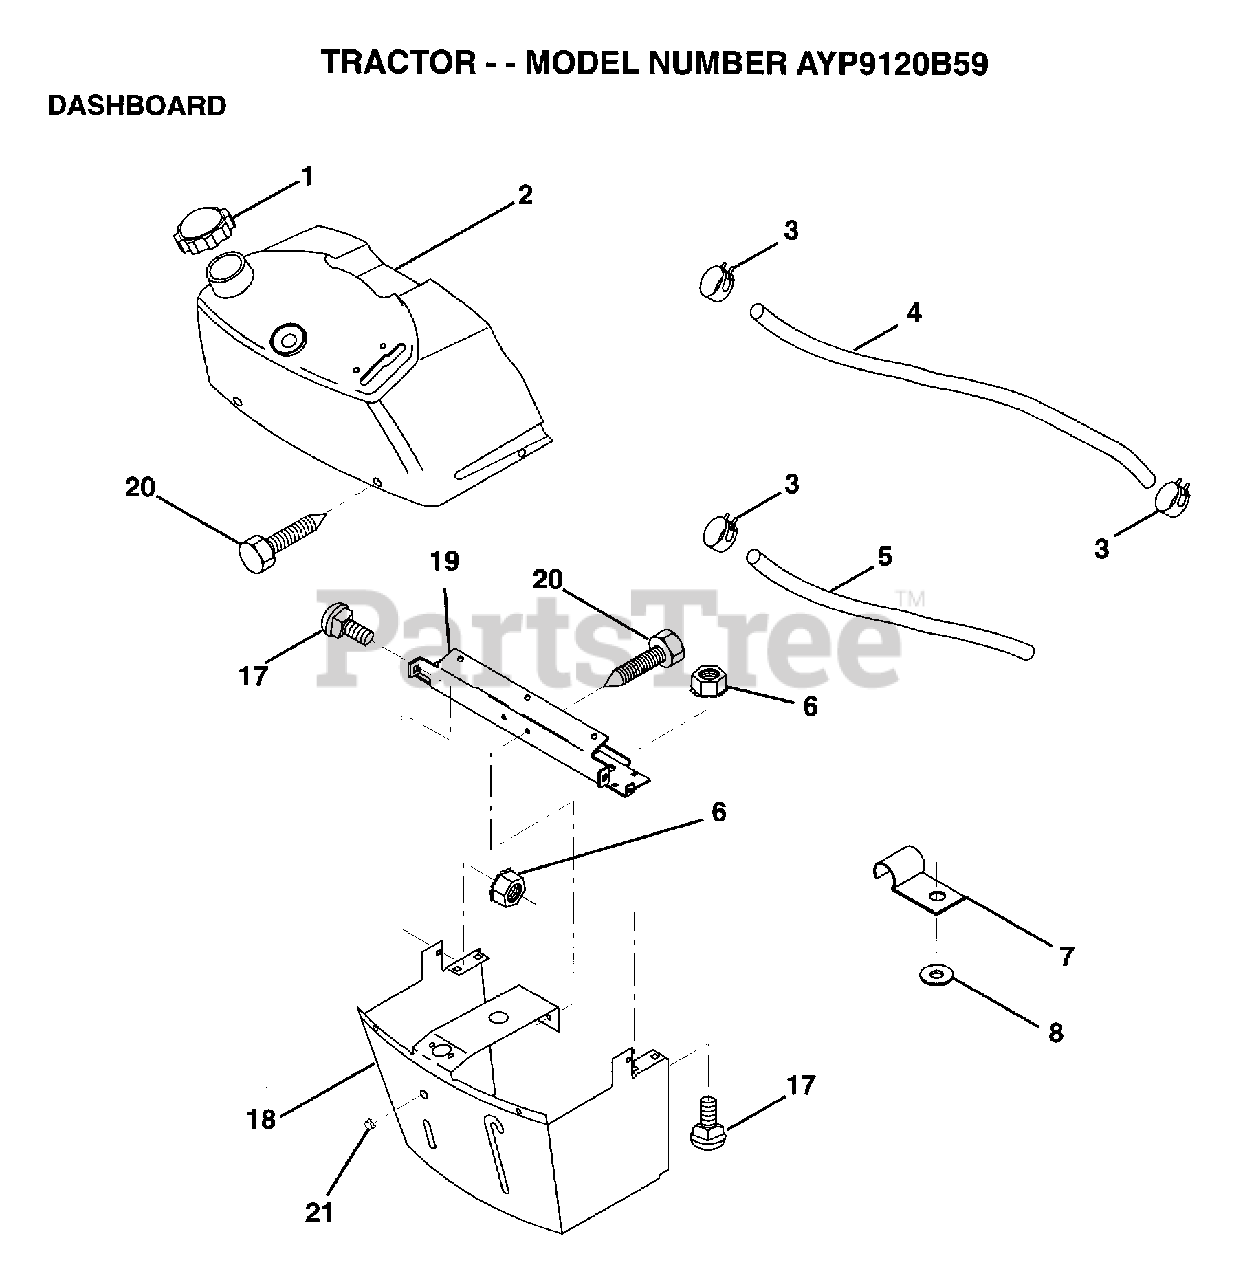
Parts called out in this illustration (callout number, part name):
1	CAP BLK FUEL LR
2	TANK.ASM.DASH.LR
3	HOSE CLAMP
5	FUEL LINE T
6	NUT HXKEP 1/4X20
7	CLIP T
8	WASHER PM
17	BOLT
18	SUPT ASM DASH
19	CROSS BRACE
20	SCREW.1/4-20X1/2
21	PLUG DOME
